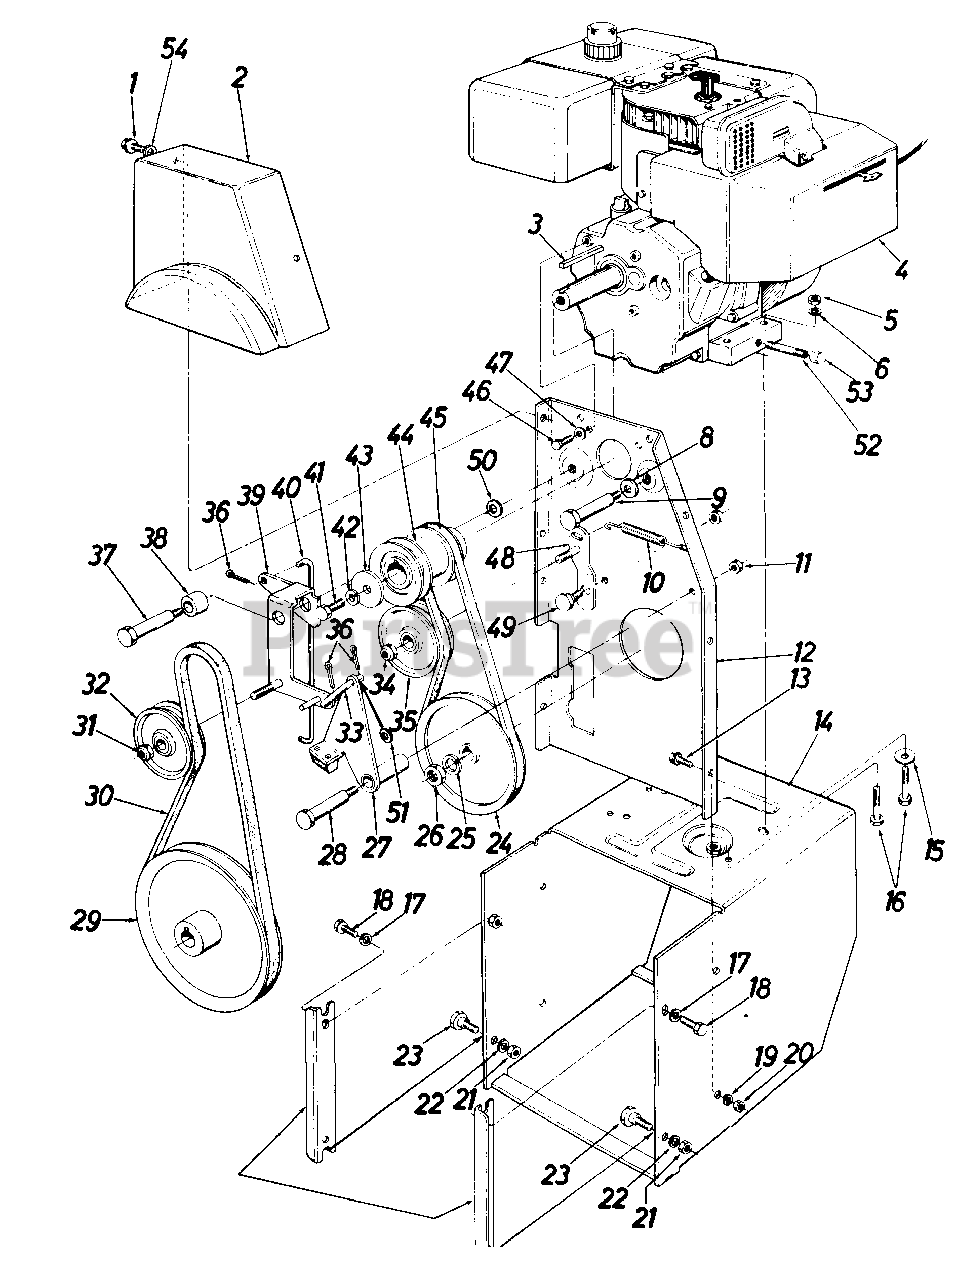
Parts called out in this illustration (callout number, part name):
1	Hex Wash. Self-Tap Scr. 5/16-24 x .50" Lg.
2	Belt Cover
3	Sq. Key 1/4" x 1.50" Lg.
4	Engine
5	Hex Nut 5/16-18 Thd.
6	L-Wash. 5/16" Scr.
8	Bell-Wash. .40 I.D. x .88 O.D.
9	Shld. Scr. .498" Dia. x 3.00" Lg.
10	Ext. Spring .38 O.D. x 3.18" Lg.
11	Hex Cent. L-Nut 3/8-16 Thd.
12	Engine Brkt. Ass'y.
13	Hex Sems Scr. 5/16-18 x .75" Lg.
14	Frame Ass'y.
15	Fl-Wash. .345 I.D. x .75 O.D. x .060
16	Hex Scr. 5/16-18 x 1.75" Lg.
17	L-Wash. 3/8" Scr. H.D.
18	Pilot Scr. 3/8-16 x .88" Lg.
19	L-Wash. 5/16" Scr.
20	Hex Nut 5/16-18 Thd.
21	Hex Nut 3/8-16 Thd.
22	L-Wash. 3/8" Scr. H.D.
23	Shld. Scr. .498" Dia. x .340" Lg.
24	V-Pulley .628 I.D. x 7.50 O.D.
25	L-Wash. for 5/8" Scr.
26	Hex Ins. Jam L-Nut 5/8-18 Thd.
27	Brake Brkt. Ass'y.
28	Shld. Scr. .498" Dia. x 2.00" Lg.
29	V-Pulley .875 I.D. x 10.12 O.D.
30	"V"-Belt 1/2 x 45.0" Lg.
31	Hex Ins. Jam L-Nut 3/8-24 Thd.
32	Fl-Idler w/Flanges 3.0 O.D.
33	Brake Linkage Ass'y.
34	Hex Ins. Jam L-Nut 3/8-24 Thd.
35	3.0" O.D. Fl-Idler w/Flanges
36	Int. Cot. Pin 5/16" Dia.
37	Shld. Scr. .625 Dia. x 2.750" Lg.
38	Spacer .63 I.D. x .75 O.D. x 1.00" Lg.
41	Hex Scr. 3/8-24 x 1.25" Lg.
42	L-Wash. 3/8" Scr. H.D.
43	Fl-Wash.
44	Engine Pulley - Double Groove
45	"V"-Belt 3/8 x 35.5" Lg.
46	Hex L-Scr. 5/16-24 x .75" Lg.
47	Bell-Wash. .345 I.D. x .88 O.D. x .060
48	Drive Idler Brkt. Ass'y.
49	Shld. Scr. - .625" Dia. x .170" Lg.
50	Bell-Wash. .40 I.D. x 1.12 O.D.
51	Fl-Wash. .34 I.D. x .750 O.D. x .05
52	Pipe Nipple - 3/8" Pipe Thd. x 3.00" Lg.
53	Hex Scr. 1/4-18 Pipe Thd.
54	Fl-Wash. .340 I.D. x .88 O.D. x .62
